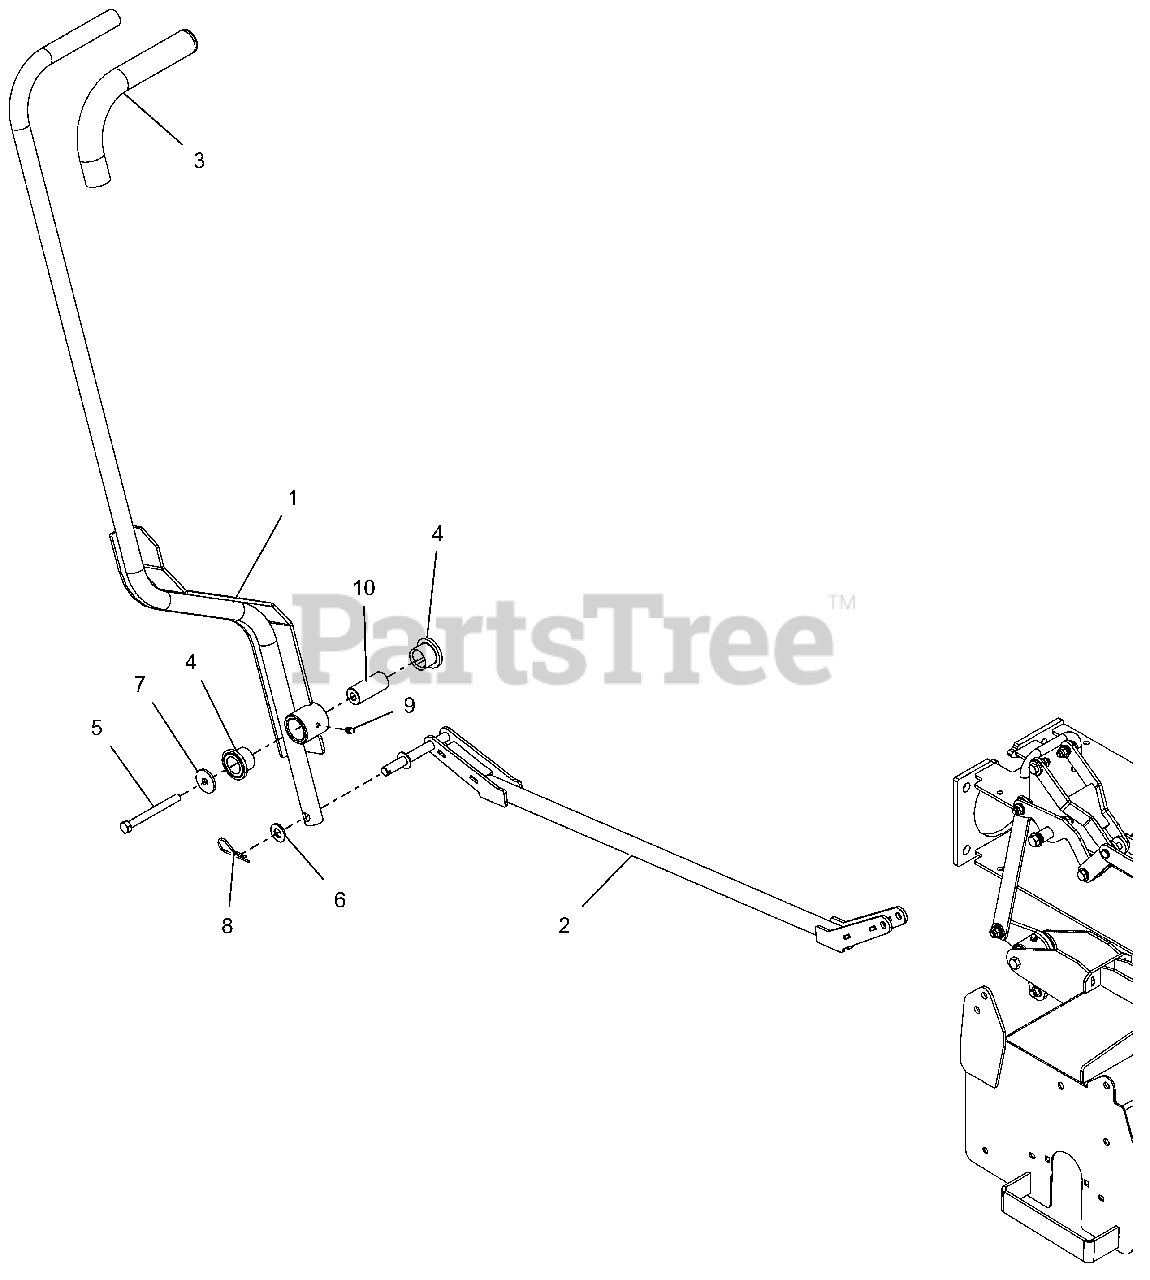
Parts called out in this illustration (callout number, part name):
1	WLDMT, LIFT HANDLE
2	WLDMT, TUBE CONNECTOR
3	GRIP, HANDLEBAR 1.00X1.38X11.3
4	BRG, FLG 1.00 X 1.25 X 1.00
5	BLT,HEX M10-1.5X100 G8.8 ZCC
6	WSHR,FLT .531X1.062X.095 ZCC
7	WSHR,FLT .406X1.375X.135 ZCC
8	PIN, HAIR-#7 .094X2.31 ZC120
9	FTG-LUBE .25-28X.256 SST
10	SPCR, PIVOT
